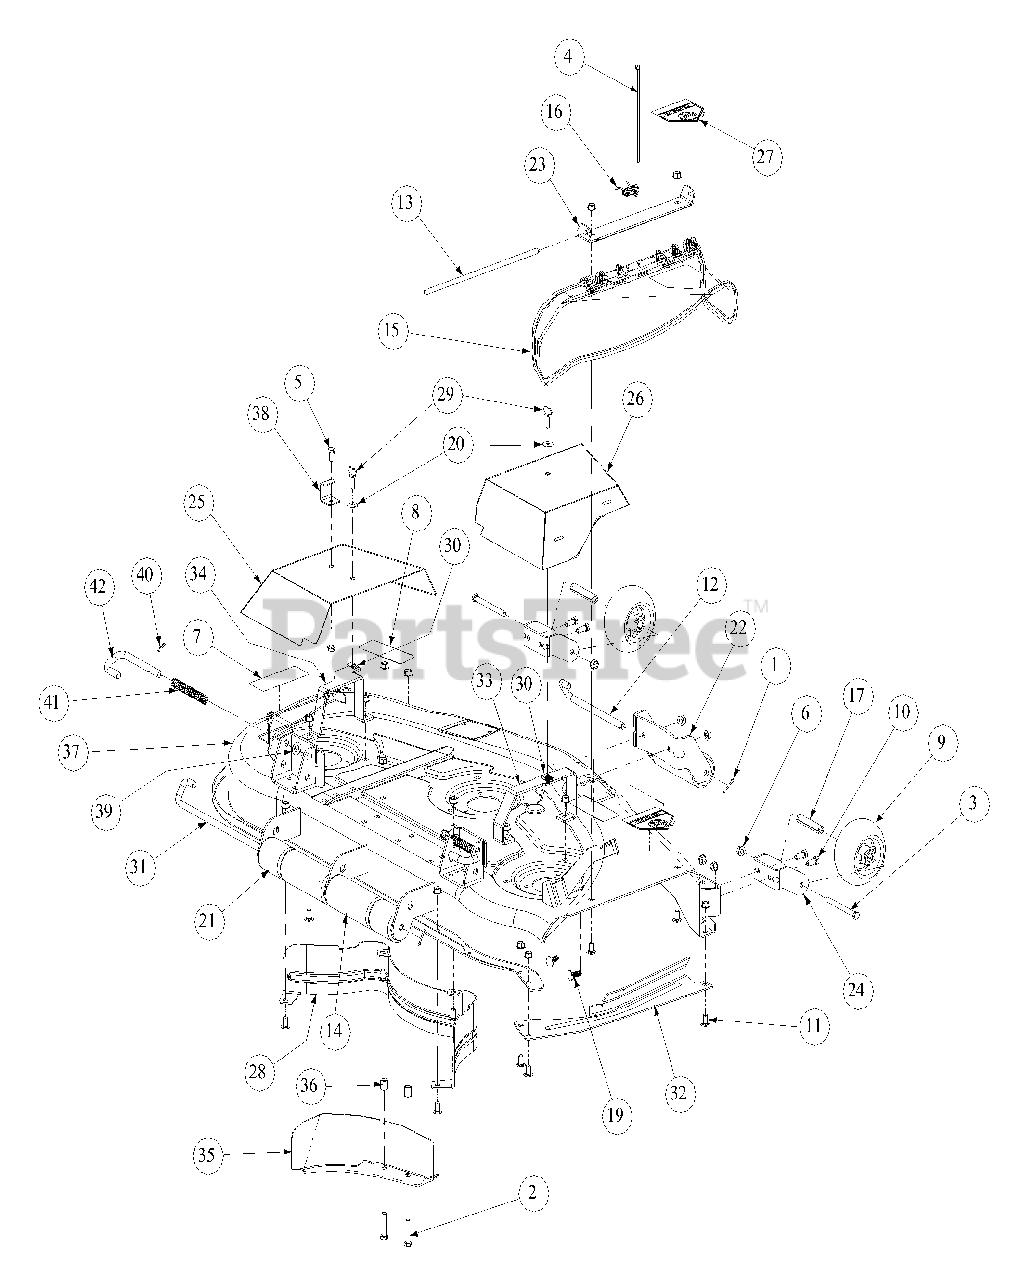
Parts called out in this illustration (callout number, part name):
1	Cotter Pin .125 Dia x 1.0
2	Capscrew, 3/8-16 x 1-3/4
3	Capscrew, 3/8-16 x 4.00
4	Cable Tie, 3/16 x .05 x 7.4
5	Hex Cap Screw 5/16-18 x .75
6	Hex Nut, 3/8-16, Flange Lock
7	Decal, Rotating Blade
8	Decal, Warning Shield Missing
9	Complete Wheel, 5.00 Dia.
10	Hex Cap Screw, 3/8-16 x .88
11	Carriage Bolt 3/8-16 x .75
12	Roller Pin 1/2 x 7.31
13	Hinge Pin, .375 x 14.06
14	Front Roller
15	Chute Deflector
16	Torsion Spring
17	Wheel Spacer
18	Lock Nut 5/16-18 Hex Flange
19	Carriage Bolt, 3/8-16 x 1
20	Washer, .325 x .930 x .045
21	Grass Catcher Roller
22	Front Roller Bracket
23	Chute Mounting Bracket
24	Castor Bracket
25	Left Hand Belt Cover
26	Right Hand Belt Cover
27	Decal, Danger Hands & Feet
29	Thumb Screw, 5/16-18 x 1.0
30	U-Nut, 5/16-18
31	Roller Rod
32	Finger Guard
33	Right Hand Belt Cover Support Bracket
34	Left Hand Belt Cover Support Bracket
35	Deck Baffle
36	Spacer, .385 ID x .75 OD x .875
37	48" Deck Weldment
38	Tension Rod Stop Bracket
39	Washer, .508 ID x 1.00 OD x .020
40	Heavy Duty Spring Pin
41	Compression Spring, .63 OD x 6.3 Lg
42	Support Pin
